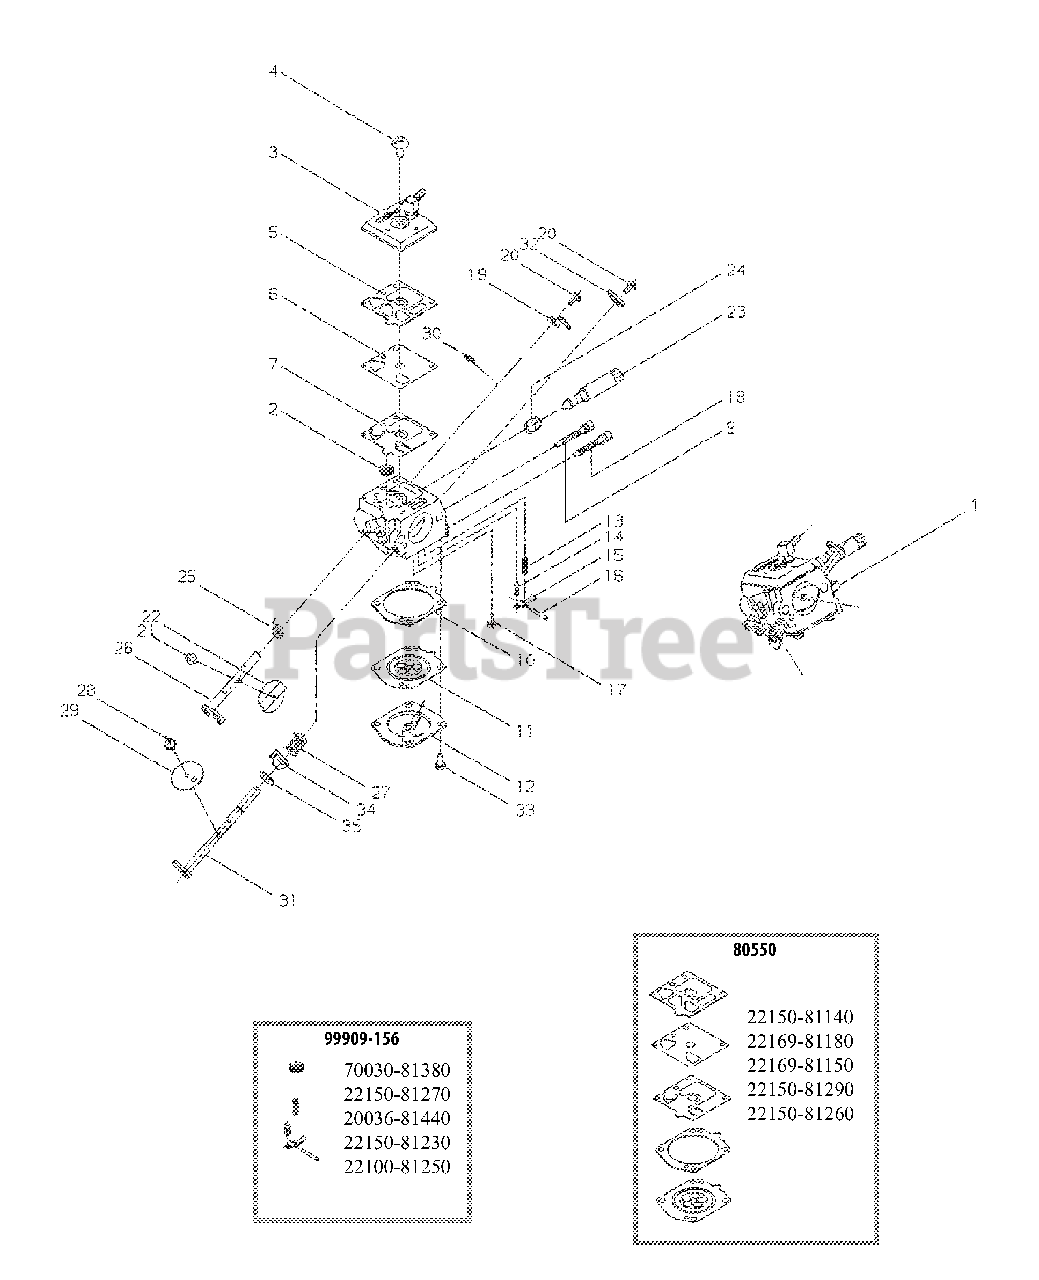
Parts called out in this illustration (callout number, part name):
1	CARBURETOR
2	SCREEN, FUEL INLET
3	COVER ASSY, PUMP
4	SCREW
5	GASKET, FUEL PUMP
6	DIAPHRAGM, PUMP
7	DIAPHRAGM, PUMP
9	NEEDLE, HIGH SPEED
10	GASKET, METERING DIAPHRAGM
11	DIAPHRAGM, METERING
12	COVER, DIAPHRAGM
13	SPRING, METERING LEVER
14	VALVE, INLET NEEDLE
15	LEVER, METERING
16	PIN, METERING LEVER
17	SCREW, METERING LEVER PIN
18	NEEDLE, HIGH SPEED
19	STOP, THROTTLE
20	SCREW
21	SCREW, THROTTLE VALVE
22	VALVE, THROTTLE
23	SCREW, IDLE ADJUST
24	SPRING, IDLE ADJUST
25	SPRING, THROTTLE RETURN
26	SHAFT, THROTTLE
27	SPRING, CHOKE RETURN
28	SCREW, THROTTLE STOP
29	VALVE, CHOKE
30	E-RING
31	SHAFT, CHOKE
32	LEVER, THROTTLE
33	SCREW
34	LEVER, FAST IDLE
35	WASHER
80550	DIAPHRAGM/GASKET KIT
99909-156	REPAIR KIT
